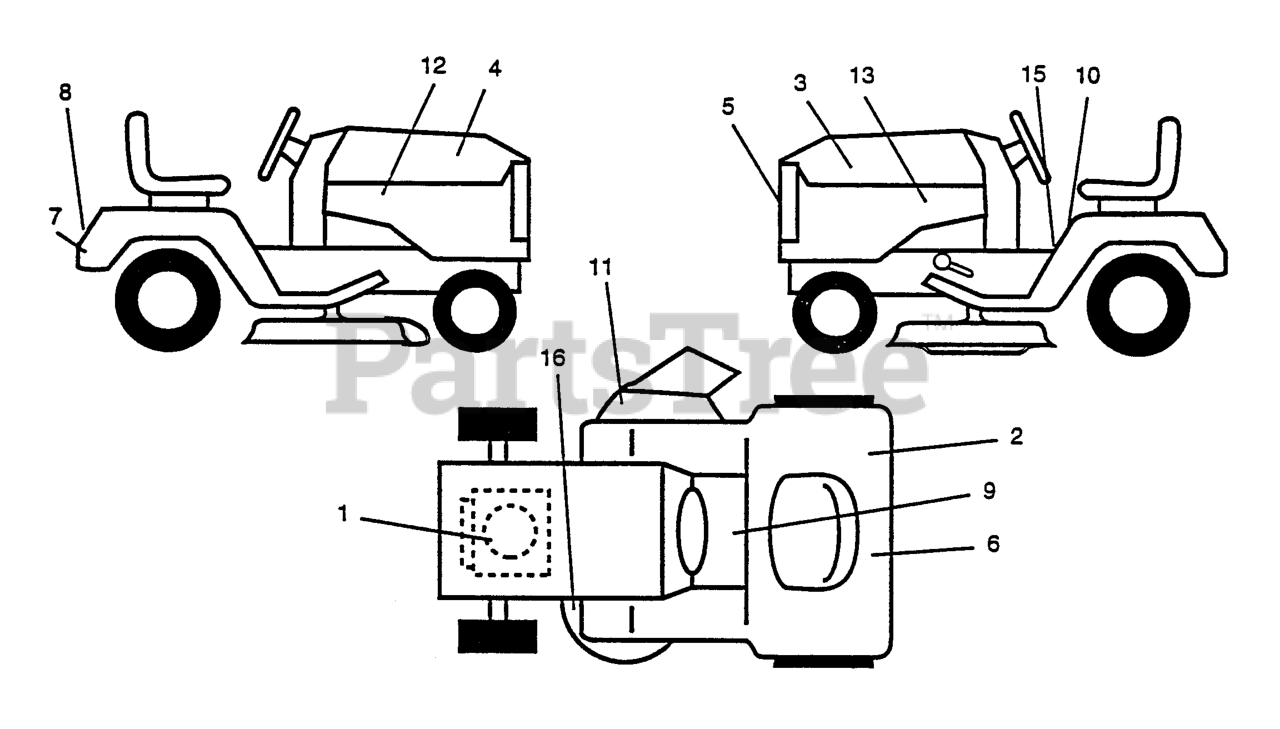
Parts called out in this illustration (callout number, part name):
1	Decal, Engine, HP
3	HOOD DECAL LH
4	HOOD DECAL RH
5	DECAL-GRILL
8	DECAL FENDER NLA
10	DECAL CAUTION
11	DECAL WARNING (ENGLISH/FRENCH)
15	DECAL OPER INSTRUCTION
16	DECAL V-BELT SCHEMATIC
